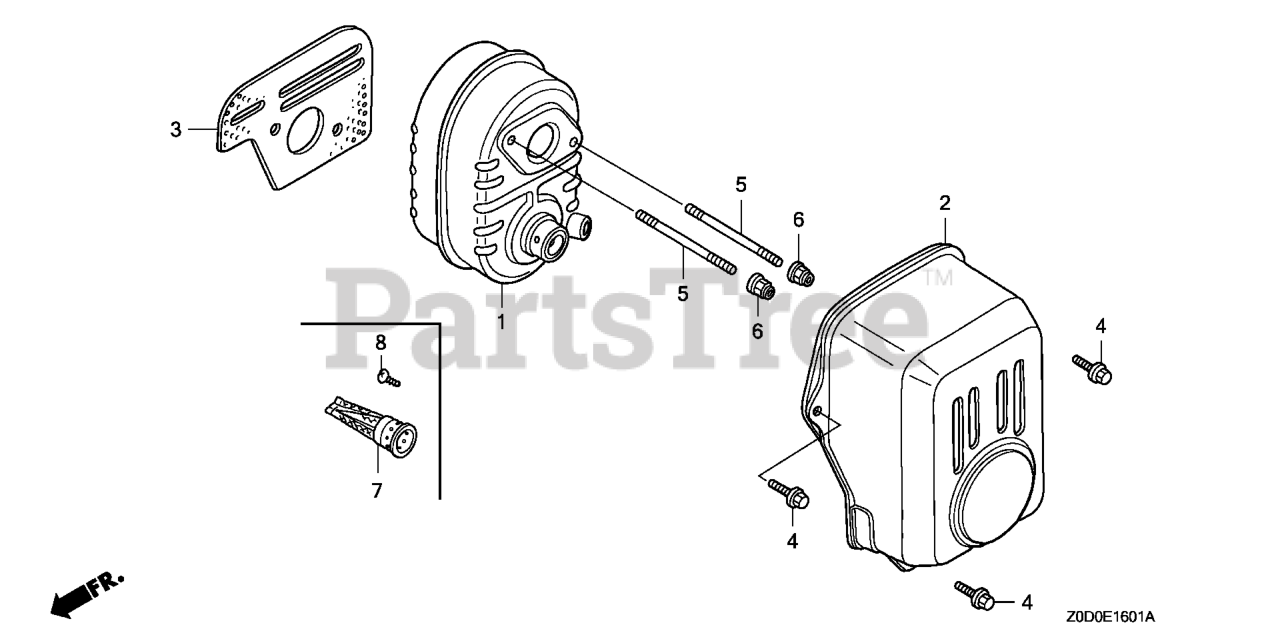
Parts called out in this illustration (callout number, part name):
2	PROTECTOR, MUFFLER
3	GASKET, MUFFLER
4	BOLT, FLANGE (6X14)
5	BOLT, STUD (6X78) (CT200)
6	NUT, SELF-LOCK (6MM)
